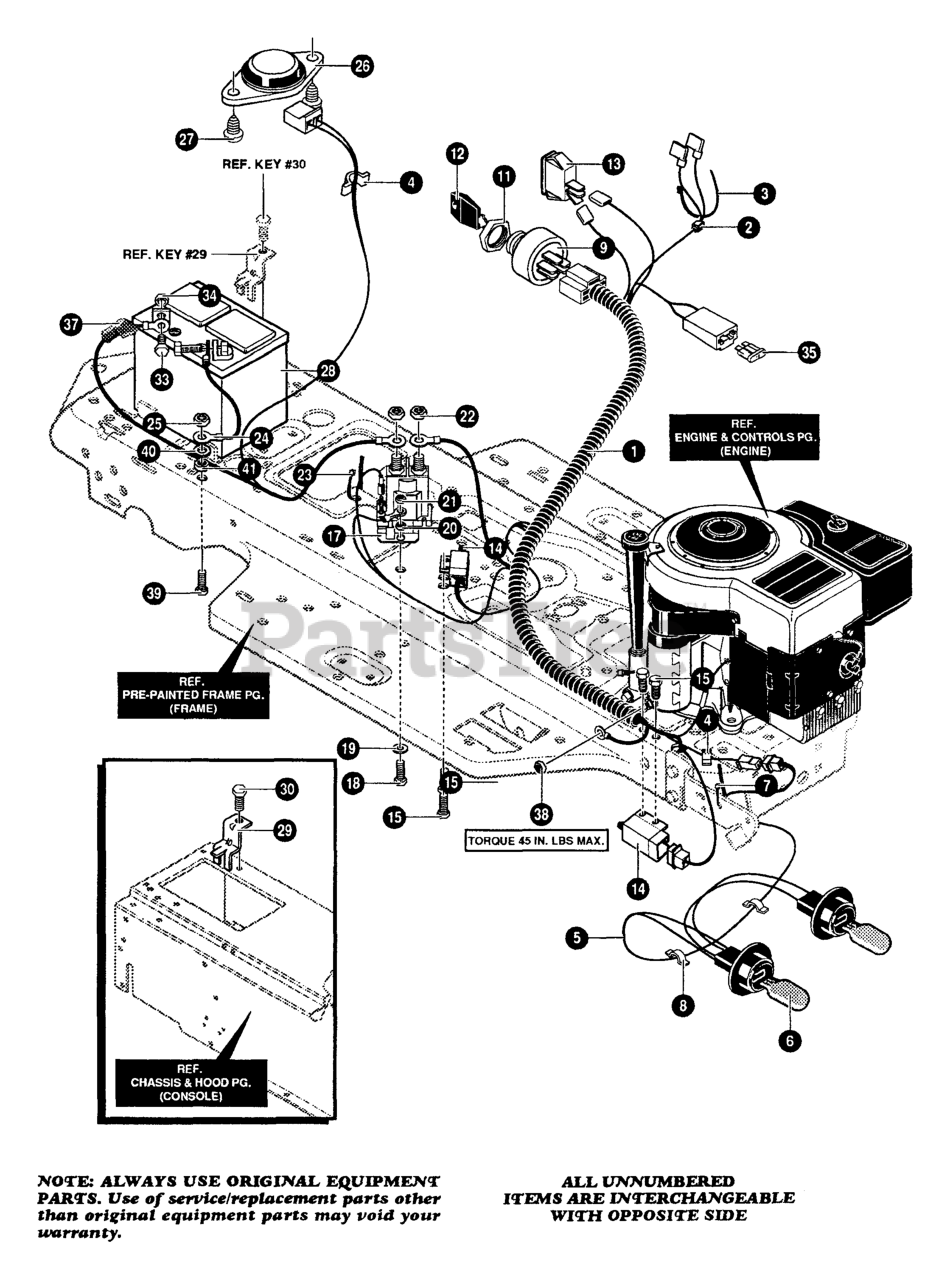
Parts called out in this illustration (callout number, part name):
1	WIRE HARNESS
2	SPLICER
3	TIE, CABLE BLACK
4	PRESS CLIP
5	ASSEMBLY, LIGHT WIRE
6	BULB, HEADLAMP
7	TIE, CABLE BLACK
8	PRESS CLIP
9	SWITCH-IGNITION
11	NUT, 5/8.8
12	KEY, IGNITION
13	LIGHT SWITCH ON/OFF
14	SWITCH, SCREW MOUNT
15	SCREW, #10 X .50
17	SOLENOID
18	SCREW, 1/4-20 x .75
19	WASHER, FLAT .281 X 1.00 x .063
20	NUT, 1/4-20
21	NUT, 1/4-20
22	NUT, 5/16-24
23	TIE, CABLE BLACK
24	WIRE, GROUND, 12.5"
25	NUT, 5/16-18
26	SWITCH, SEAT
27	SCREW, 1/4-20 X .38
28	BATTERY, 12V
29	BATTERY BRACKET
30	SCREW, 1/4-20 x .50
33	SCREW, 1/4-20 X .75
34	NUT, 1/4-20
35	FUSE
37	INSULATOR, BATTERY BOOT
38	NUT, 1/4-20
39	SCREW, 5/16-18 x 1.00
40	WASHER, .320 X .61 X .03
41	NUT, 5/16-18
